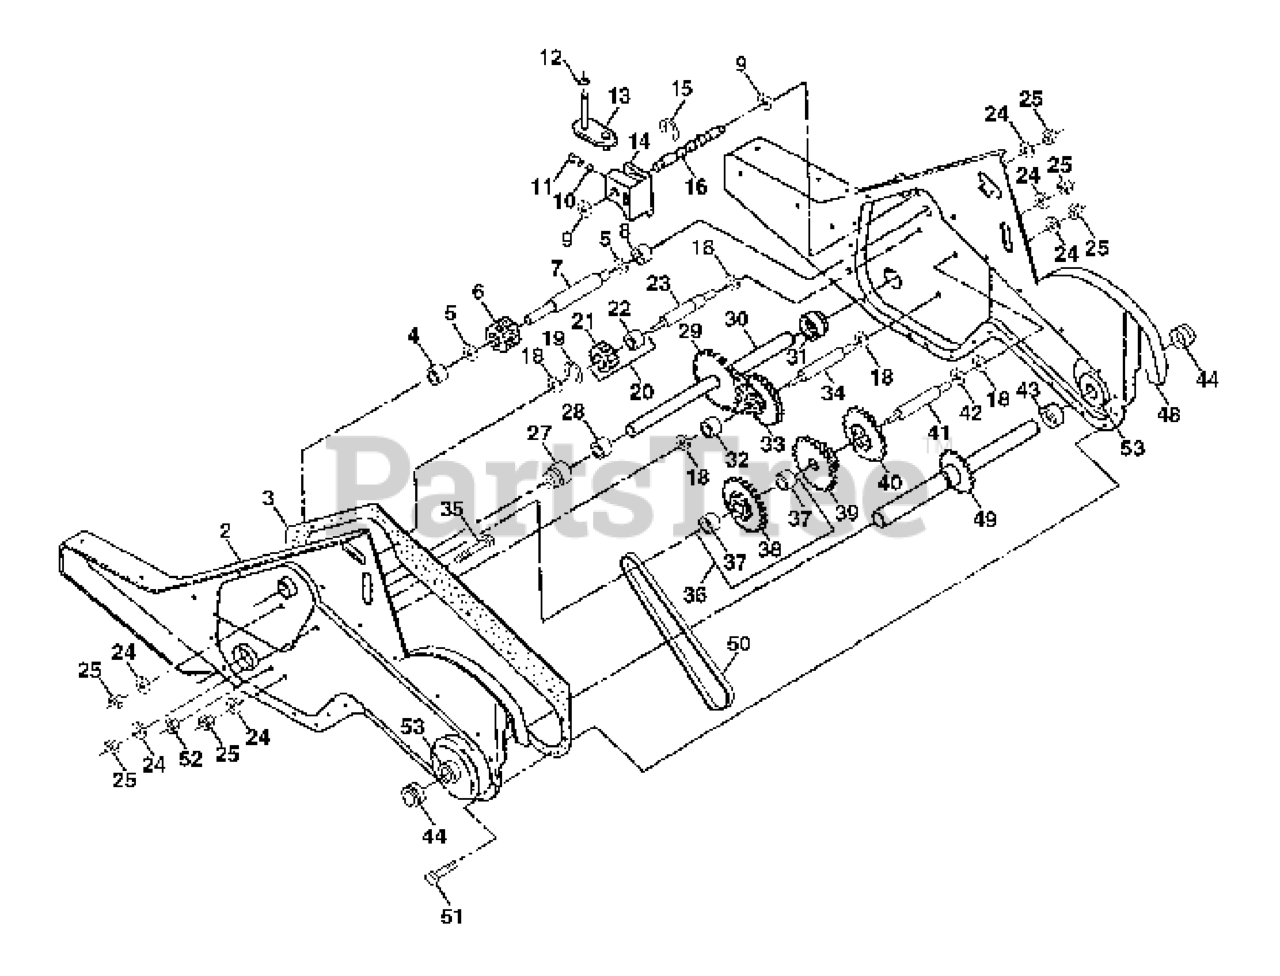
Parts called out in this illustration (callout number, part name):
1	TRANSMISSION ASSY
2	GEARCASE LH W/BRG
3	GASKET TI
4	NEEDLE BRNG LT
5	THRUST WASHER
6	GEAR.PINION.INPUT
7	SHAFT.INPUT."D".TILLER
8	BEARING TI
9	WASHER, SEAL (2 2)
10	STEEL BALL KIT
11	SPRING-SHIFT CRT
13	BRACKET ASM.SHIFT.CRT
14	SHIFT FORK TI
16	SHAFT.SHIFTER.TILLER
20	GEAR ASSY CRT
21	GEAR-REV IDLR CRT
22	NEEDLE BEARING TI
24	LOCKWASHER
25	NUT.ASF.HEX.7/16
27	BEARING, SHAFT LH CRT
30	GROUND SHAFT ASS'Y
31	BEARING, SHAFT RH CRT
33	SPRCKT 8 GEAR CRT
34	SHAFT.SECONDARY.REDUCTION.CRT
35	SCRW WHIZ LOK CRT
36	SPROCKET.ASM.W/BEARING.TILLER
37	BEARING
38	SPROCKET, TINE
41	SHAFT.REDUCTION.TILLER
42	BRNG RACE T
44	SEAL ASM, OIL
48	GEARCASE RH W/BRG
49	TINE SHAFT
50	CHAIN.TILLER
51	SCREW
52	NUT
53	BEARING KIT
